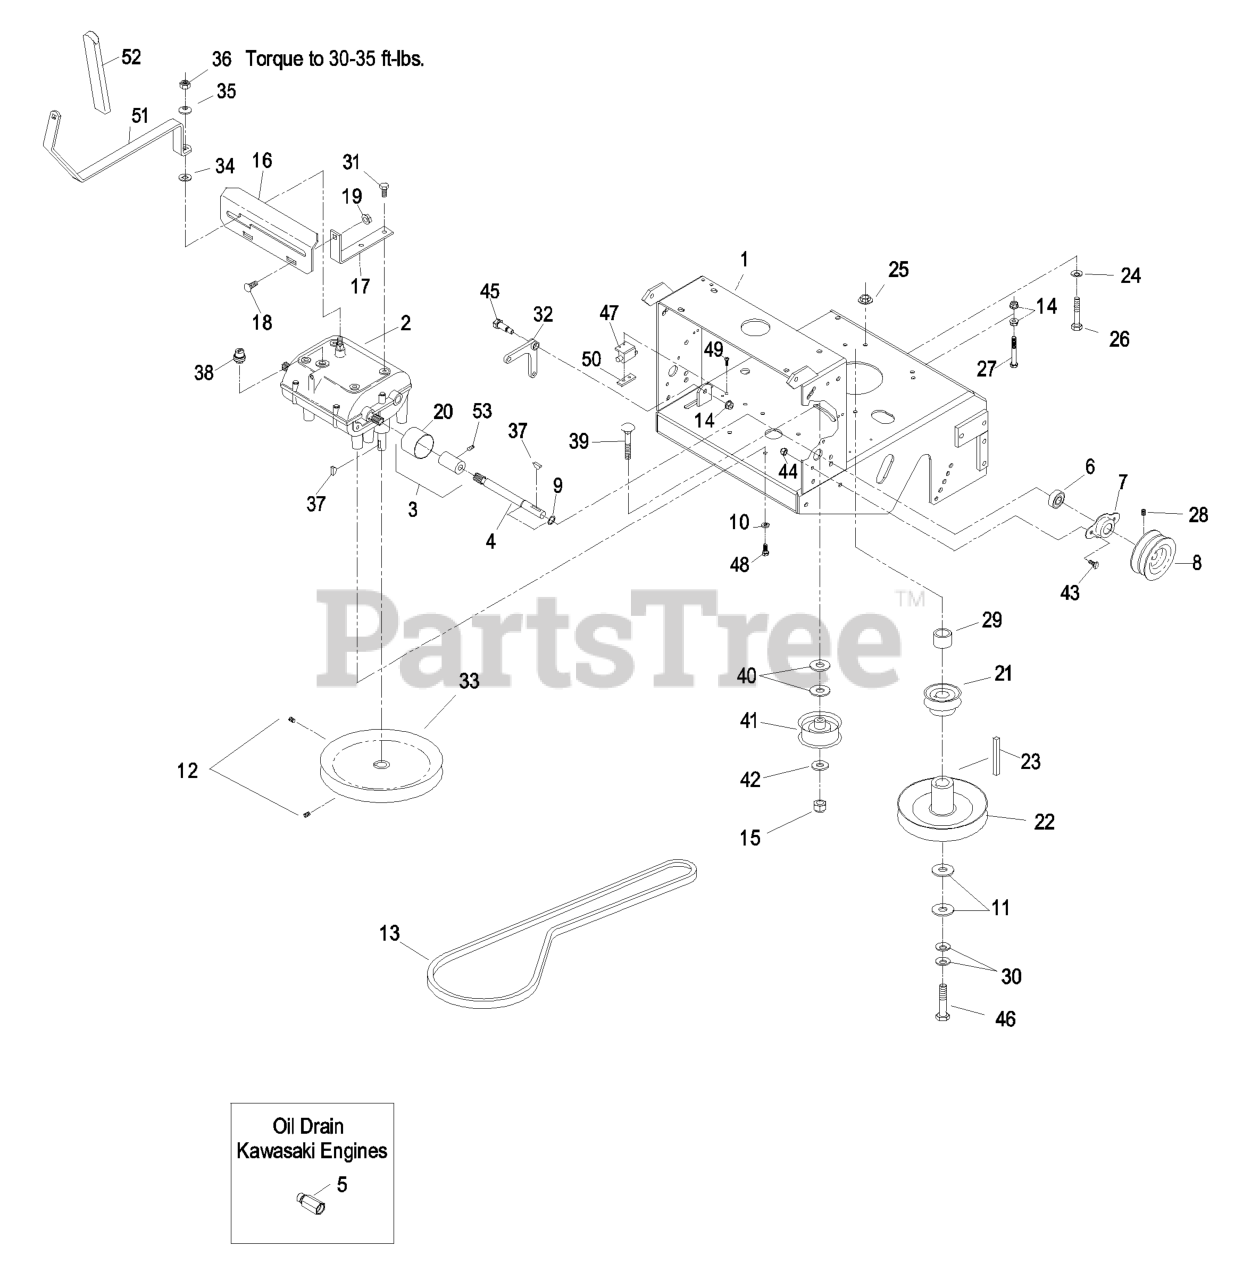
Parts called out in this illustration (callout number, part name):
3	ASM,COUPLER/ZERK
4	SHAFT-TRANSMISSION
5	ADAPTER
6	BEARING-SHAFT
7	FLANGE-OUTPUT
8	SHEAVE-TRANSMISSION
9	RING-RETAINING
10	WASHER-LOCK
12	SCREW-HSH
13	BELT,TRANS DRIVE
14	NUT-HHF, WHIZ
15	NUT-LOCK, NI
16	PLATE,SHIFTER W/DECAL
17	BRACKET-PLATE, SHIFT
18	BOLT-CARR
20	GUARD-COUPLER
21	SHEAVE-TRANSMISSION
23	KEY-SQUARE
24	WASHER-SPRING
26	SCREW-HH
27	SCREW-HH
28	SCREW-SET
29	SPACER-CLUTCH
30	WASHER-SPRING
31	SCREW-HWH, THREAD CUT
32	BELLCRANK
33	SHEAVE-TRANSMISSION
35	WASHER-BELLEVILLE
36	NUT-LOCK
37	KEY-WOODRUFF
38	SWITCH-START, NEUTRAL
39	SCREW-HH
40	WASHER-FLAT
42	WASHER-FLAT
43	SCREW-HH
44	NUT-LOCK, NI
45	BOLT-SHOULDER
46	SCREW-HH
47	SWITCH-OPEN, NORMALLY
48	SCREW-HH
49	SCREW-PPH
50	PLATE-TAPPED
51	ASM,SHIFT LEVER
52	GRIP,FOAM
53	FITTING-GREASE
